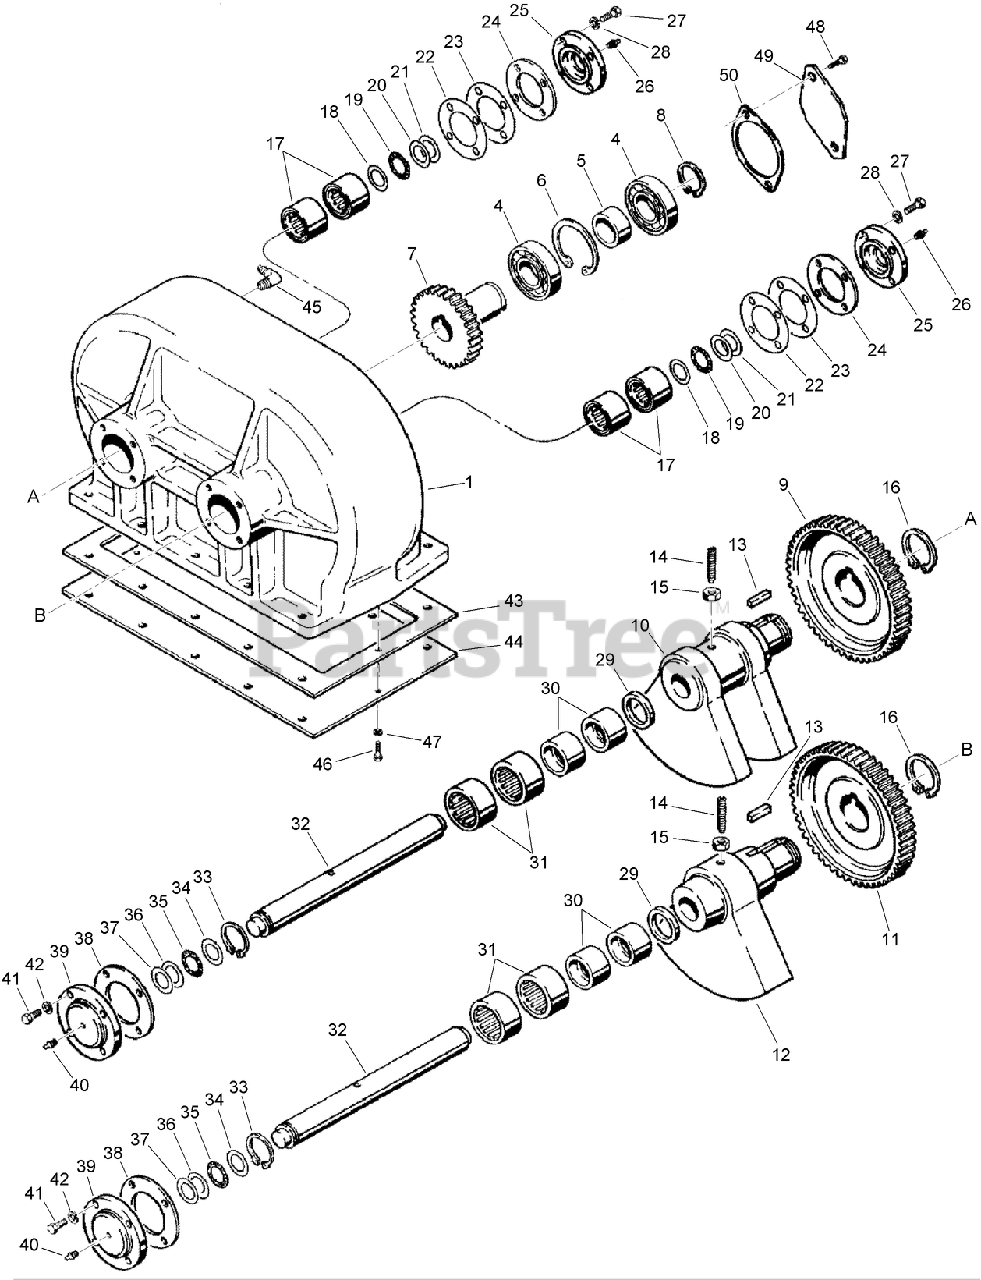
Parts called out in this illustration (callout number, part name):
1	HOUSING-gearbox
4	BEARING
6	RING-internal retaining, No. 315, bearing and shaft retaining
7	GEAR-DRIVE, PLOW
8	RING-snap
10	WEIGHT-COUNTER
12	WEIGHT-COUNTER
13	KEY-SQUARE
14	SCREW-SET, HSH
15	NUT-JAM
16	RING-RETAINING
17	BEARING
18	WASHER-thrust, 0.81 mm (0.032 inch) thick, shaft bearing
19	BEARING
20	WASHER-THRUST
21	WASHER-thrust, 0.81 mm (0.032 inch) thick, shaft bearing
22	GASKET-SHIM
23	GASKET-SHIM
25	CAP-BEARING
26	FITTING-Lube 1/4-28 Tpr SAE-LT .54 Long
27	BOLT-Hex, 5/16 NC x 1-1/4 inch
28	WASHER-Lock, 5/16 inch
30	BEARING
31	BEARING - Counterweight Shaft, Rear
32	SHAFT-BEARING
33	RING-external retaining, No. 150, shaft
34	WASHER-thrust, 0.81 mm (0.032 inch) thick, shaft bearing
35	BEARING
36	WASHER-THRUST
37	WASHER-thrust, 0.81 mm (0.032 inch) thick, shaft bearing
39	CAP-BEARING
40	FITTING-Lube 1/4-28 Tpr SAE-LT .54 Long
41	BOLT-Hex, 5/16 NC x 1-1/4 inch
42	WASHER-Lock, 5/16 inch
43	GASKET-GEARCASE
44	PLATE-COVER
45	FITTING-ELBOW, 90
46	SCREW-HH
47	WASHER-Spring Lock, Reg 3/8 ZND
48	SCREW-HH
49	PLATE-discard to mount plow motor
50	GASKET-124 x 146 x 0.8 mm, motor
